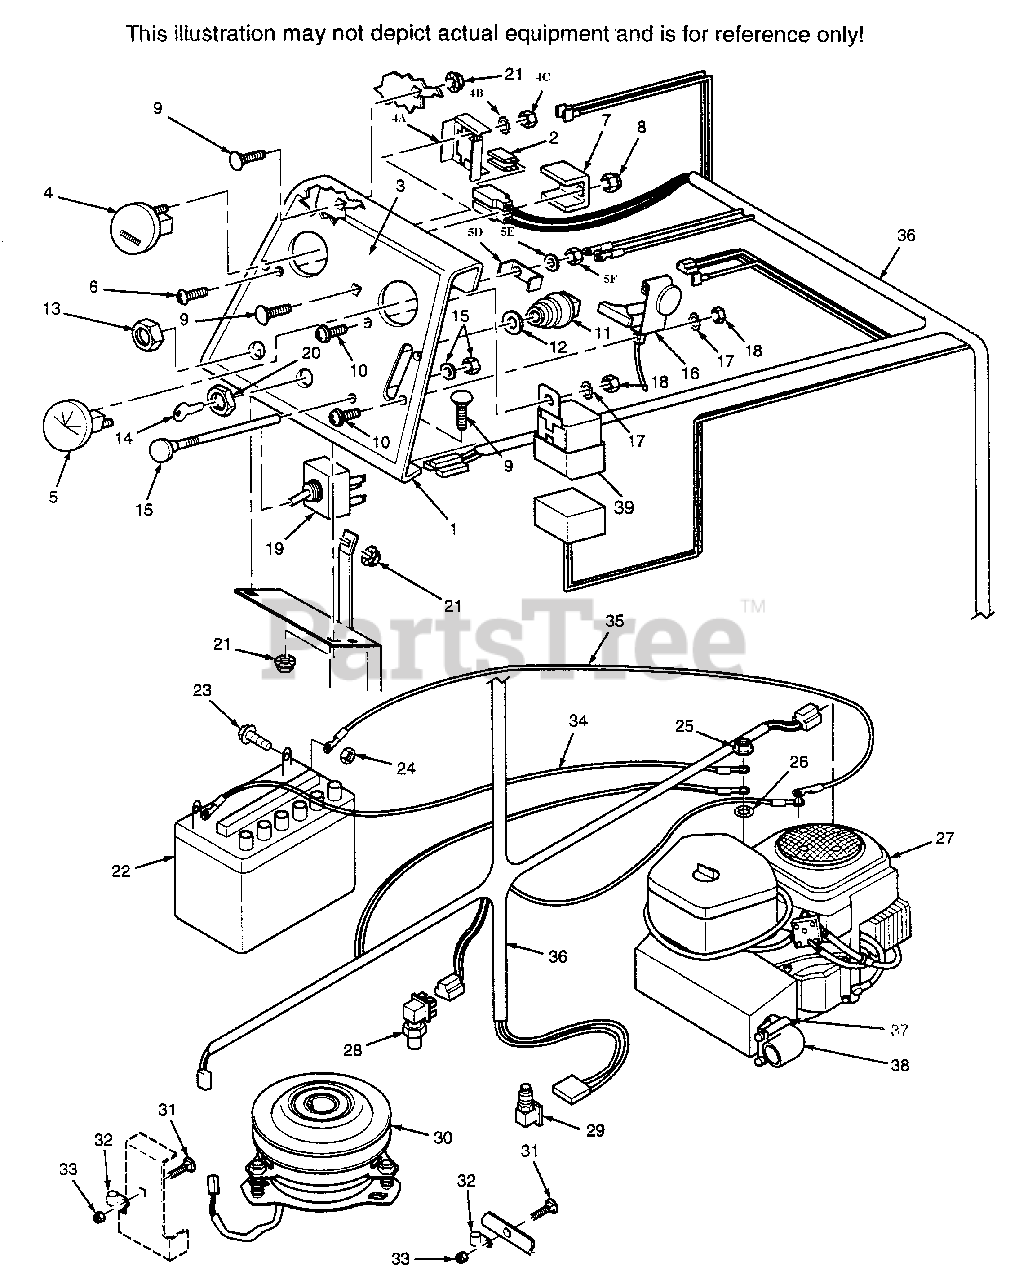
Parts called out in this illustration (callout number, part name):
1	INSTRUMENT PANEL(INCLUDES DECAL)
2	BLADE FUSE, 20 AMP.
3	DECAL, INSTRUMENT PANEL
4	HOUR METER(INC. BRACKET & HARDWARE 4A,
4A	HOUR METER BRACKET
4B	LOCKWASHER, #10 EXT. TOOTH
5	AMMETER(INC. BRACKET AND HARDWARE 5D,
5D	AMMETER BRACKET
5E	LOCKWASHER, #10 INT. TOOTH
7	BRACKET, FUSE HOLDER
10	PHILLIPS WASHER HEAD SCREW,
11	KEYSWITCH
12	LOCKWASHER, 5/8 INT. TOOTH
14	IGNITION KEY AND RING ASSY.
15	CHOKE CONTROL(INCLUDES HARDWARE)
16	THROTTLE CONTROL
17	LOCKWASHER, #10 EXT. TOOTH
19	SWITCH, PTO
21	SERR. FL. HH NUT, 5/16-18
22	BATTERY
25	SERR FL. HEX HEAD NUT 5/16-18
26	LOCKWASHER 5/16 INT. TOOTH
27	ENGINE, 20 HP KOHLER CV
27	ENGINE, 22 HP KOHLER CV
28	SWITCH, PARKING BRAKE
29	SWITCH, FOOT SAFETY
30	CLUTCH, ELECTRIC
32	WIRELOOM
34	BATTERY CABLE, 36" BLACK
35	BATTERY CABLE, 25" RED
36	WIRE HARNESS, STHM
37	CLAMP
38	ELBOW
39	RELAY
